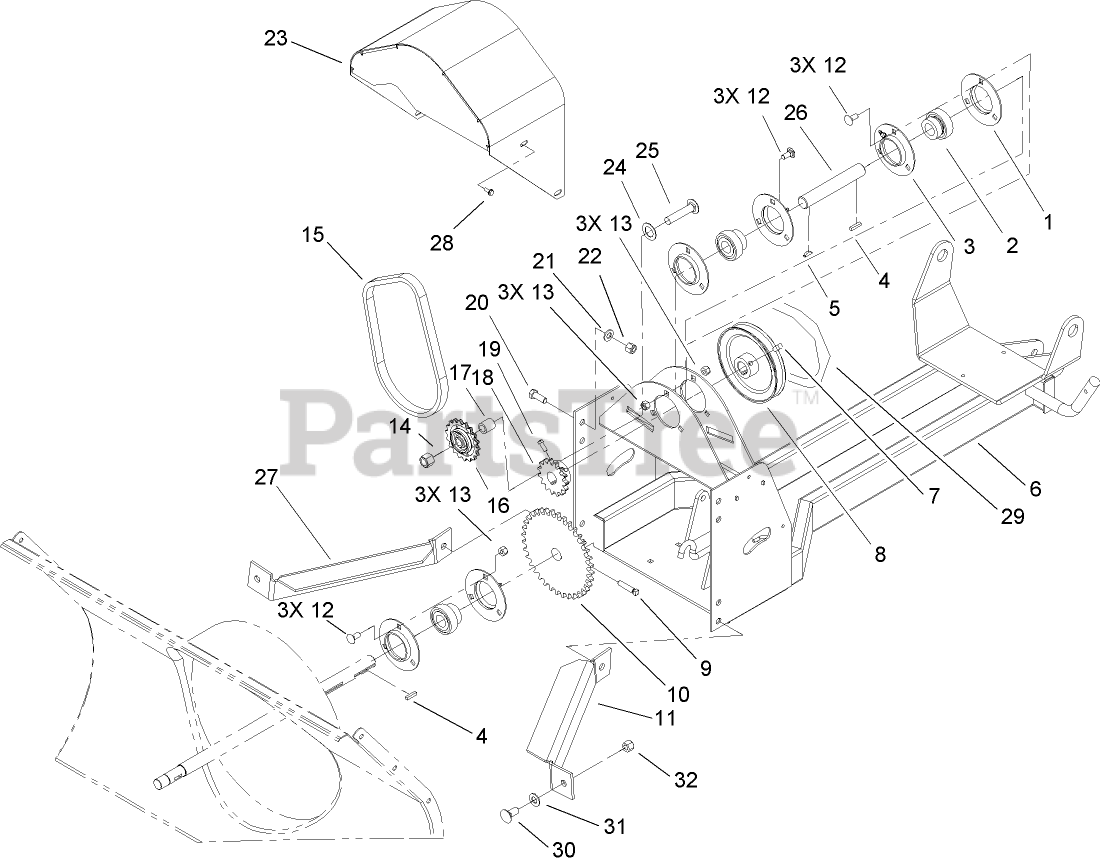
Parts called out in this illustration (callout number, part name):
1	Flange
2	BEARING AND COLLAR
3	FLANGE-RELUBE
4	KEY
5	KEY-HI PRO
6	FRAME ASM
7	SCREW-SQH
8	PULLEY - GEAR BOX
9	SCREW-SET
10	SPROCKET - 38 TOOTH
11	BRACE-HOUSING LH
12	BOLT-CARR
13	NUT-LOCK, NI
14	NUT-LOCK, NI
15	CHAIN-DRIVE
16	SPROCKET-IDLER
17	SPACER-IDLER
18	SPROCKET-15 T
19	SCREW-SET
20	SCREW-HH
21	WASHER-FLAT
22	NUT-LOCK, NI
23	BELT COVER ASM
24	WASHER
25	SCREW-CARR
26	SHAFT-JACK
27	BRACE-HOUSING RH
28	SCREW-TAPTITE
29	V-BELT
30	SCREW-CARR
31	WASHER-FLAT
32	NUT-LOCK, NI
